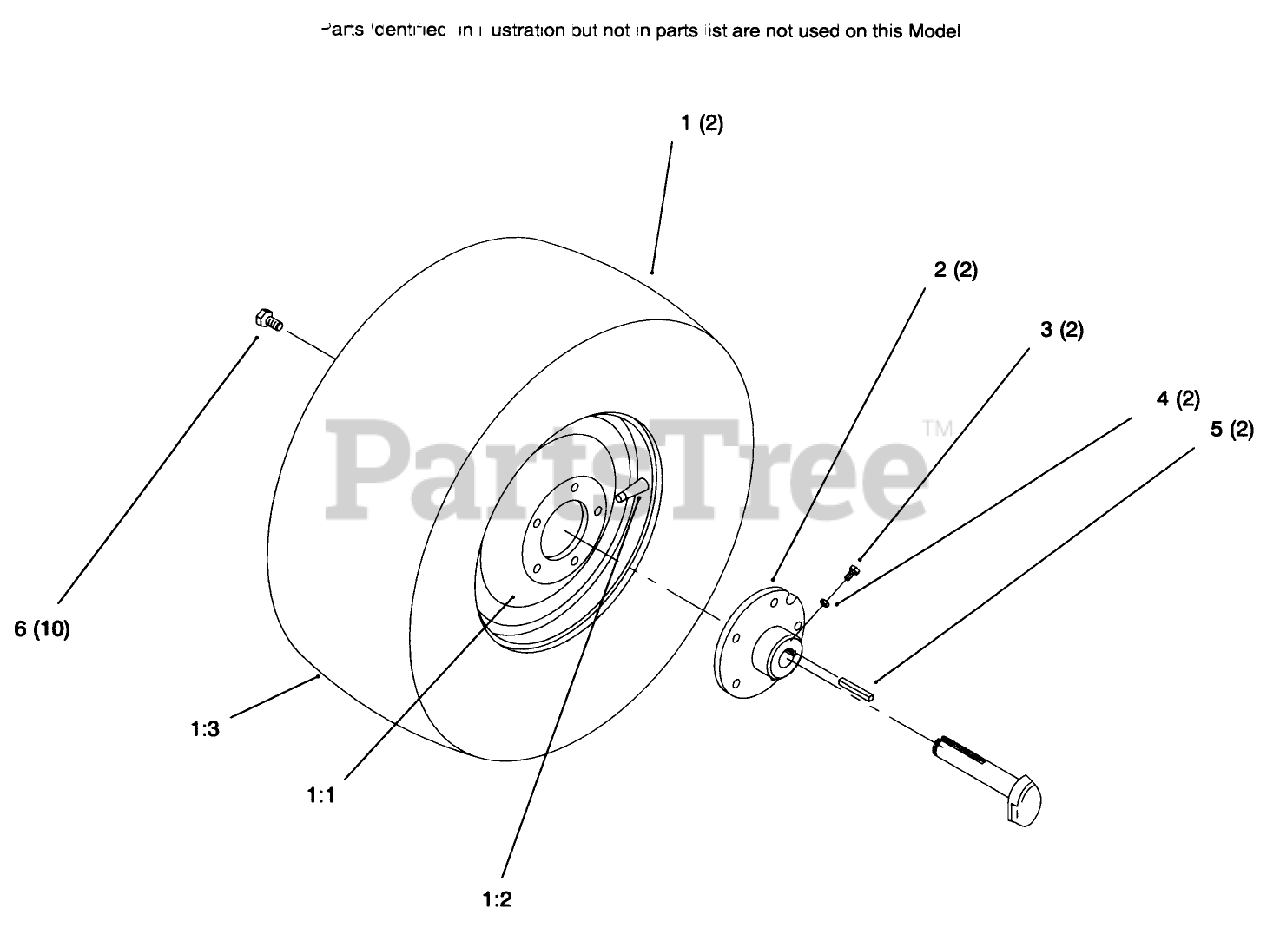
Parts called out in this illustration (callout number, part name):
1	Wheel Tire ASM Rear
1:1	WHEEL
1:2	VALVE
2	HUB-WHEEL
3	SCREW-SET, SQH
4	NUT-JAM
5	KEY-SQUARE
6	BOLT-LUG
